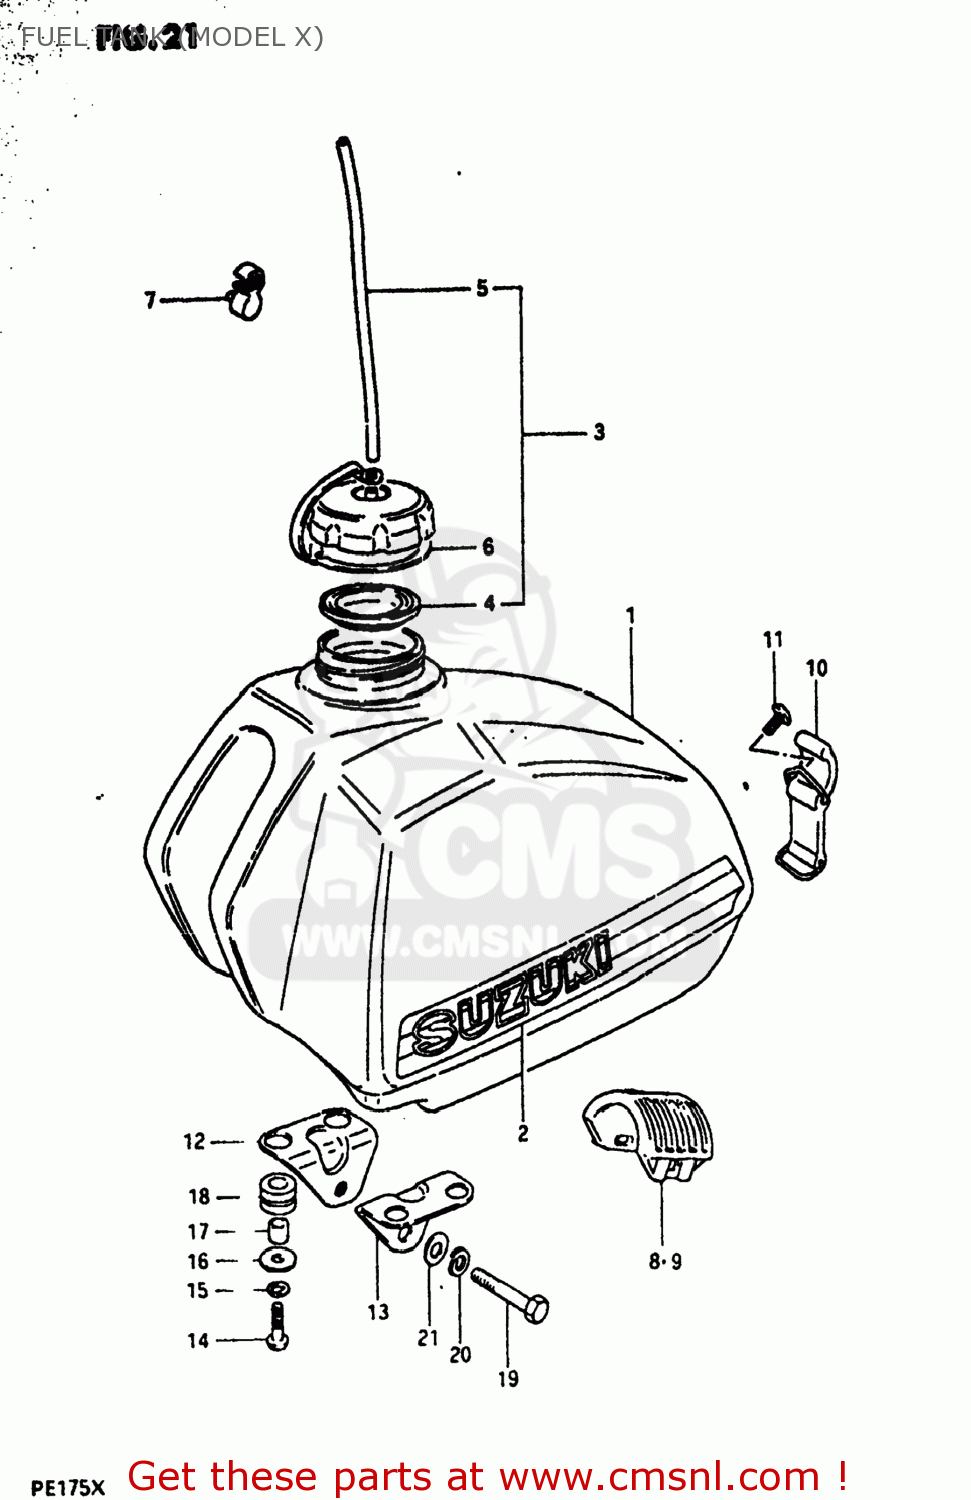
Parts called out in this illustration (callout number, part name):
1	TANK ASSEMBLY,FUEL
2	TAPE SET,FUEL TANK
3	CAP,FUEL TANK
4	GASKET,FUEL TANK CAP (NAS)
5	HOSE
6	BAND,FUEL TANK CAP
7	CLAMP,BREATHER HOSE
8	CUSHION,FUEL TANK
9	CUSHION,FUEL TANK
10	BAND
11	SCREW(6X18)
12	BRACKET,FUEL TANK,LOWER
13	BRACKET,FUEL TANK
14	SCREW
15	LOCK WASHER
16	WASHER (6.5X24X1.6)
17	SPACER(6.8X12X11)
18	CUSHION
19	HEXAGON BOLT 8X80
20	LOCK WASHER
21	WASHER
